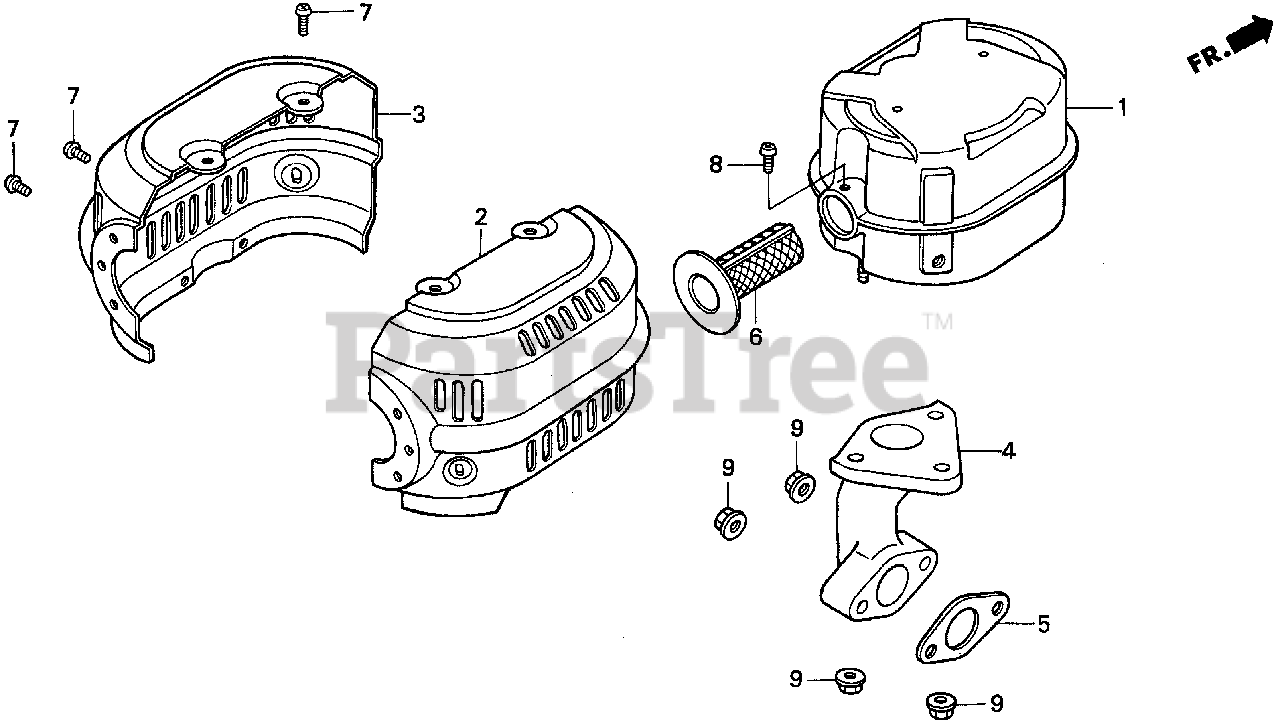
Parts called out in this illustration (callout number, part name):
1	MUFFLER (SILENT)
2	PROTECTOR, R. MUFFLER (SILENT)
3	PROTECTOR, L. MUFFLER (SILENT)
4	PIPE, EX.
5	GASKET, EX. PIPE Use up to Engine SN 2949254.
5	GASKET, EX. PIPE (WACKER)
6	ARRESTER, SPARK
7	SCREW, TAPPING (5X8)
8	SCREW, TAPPING (4X6) (TO INSTALL OPTIONAL SPARK ARRESTER)
9	NUT, FLANGE (8MM)
